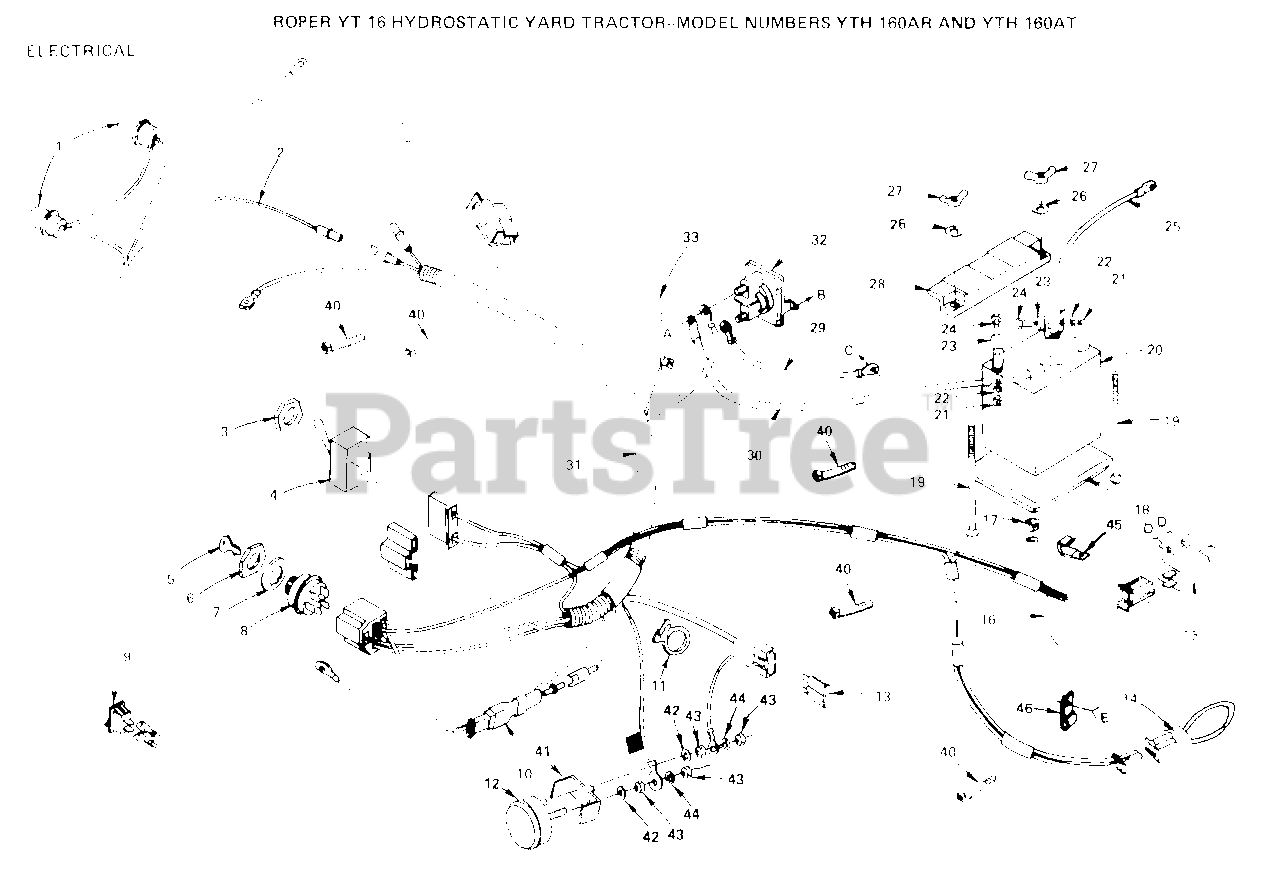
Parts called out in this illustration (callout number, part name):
1	HEADLAMP BULB
3	HEX NUT T
4	SWITCH.PTO.T
6	CONDUIT NUT L
7	LOCKWASHER
12	AMMETER T
13	FUSE HYT
15	SWITCH-INTER. GT
18	"TRAY T, BATTERY"
19	BOLT
22	LOCKWASHER
23	WASHER
24	BOLT LT
25	CABLE T
26	LOCKWASHER GT
30	CABLE-BATTERY T
40	WIRE TIE
45	CLIP GTV
46	CLIPT
